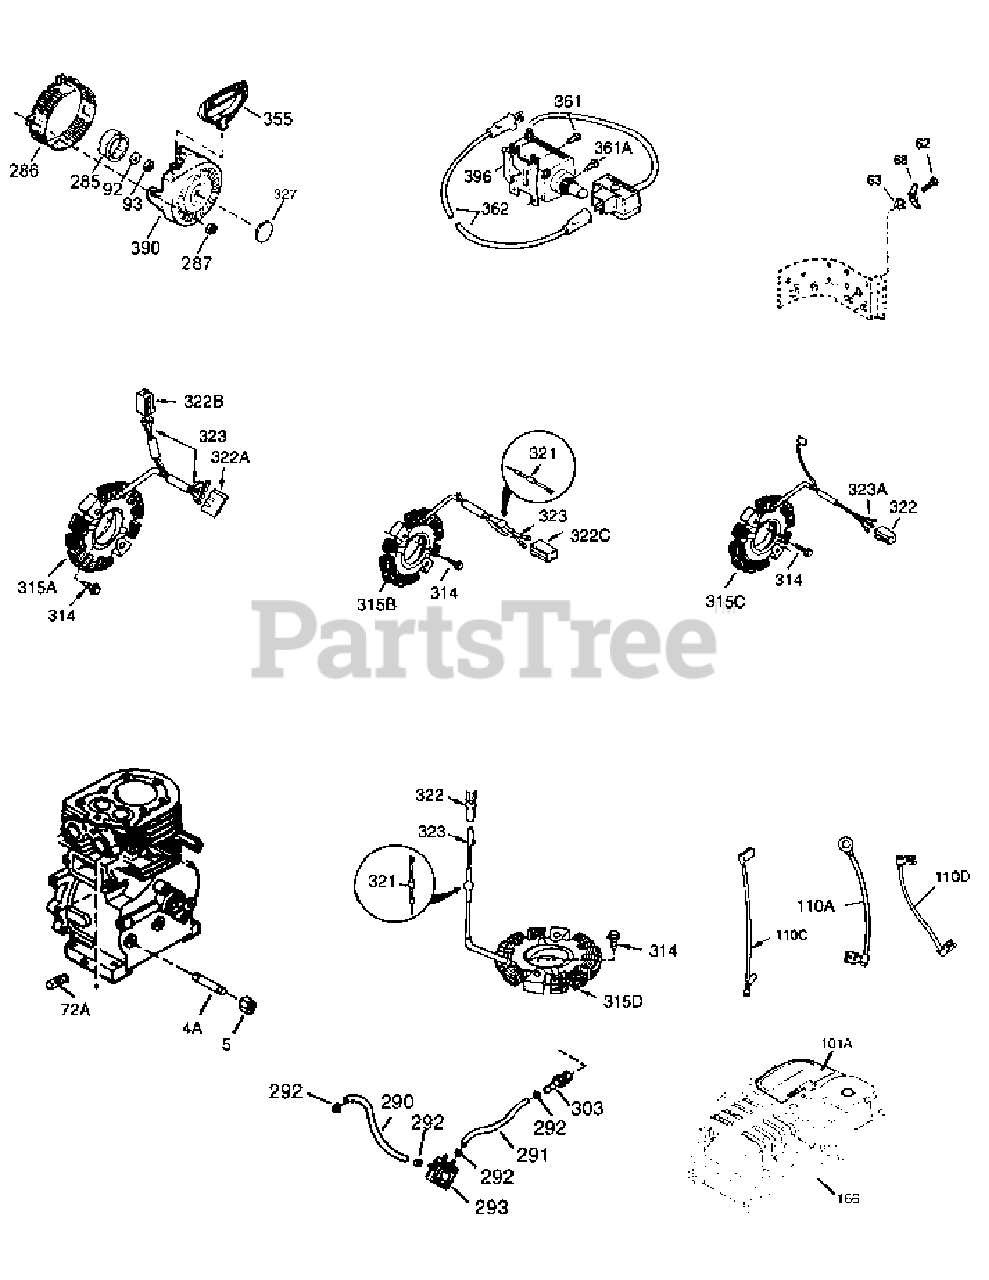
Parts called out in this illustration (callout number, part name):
5	Extension Cap,1/4-18 NPT
18	Screw, T-15, 8-32 x 7/16"
92	Belleville Washer
93	Flywheel Nut 5/8-18
110A	Ground Wire 10.50" with male & female flag terminals
128	Belleville Washer
285	Starter Cup
290	Fuel Line 32.0" length
292	Fuel Line Clamp
314	Screw, 1/4-20 x 3/4"
322	Connector Body
355	Starter Handle Mitten Grip
361	Screw, T-30, 1/4-20 x 15/32"
361A	Screw, 6-32 x 2-1/2"
390	Rewind Starter
396	Electric Starter Motor 120 Volt
702	Screw, 5/16-18 x 1-25/32"
999	Winter Maintenance Kit
